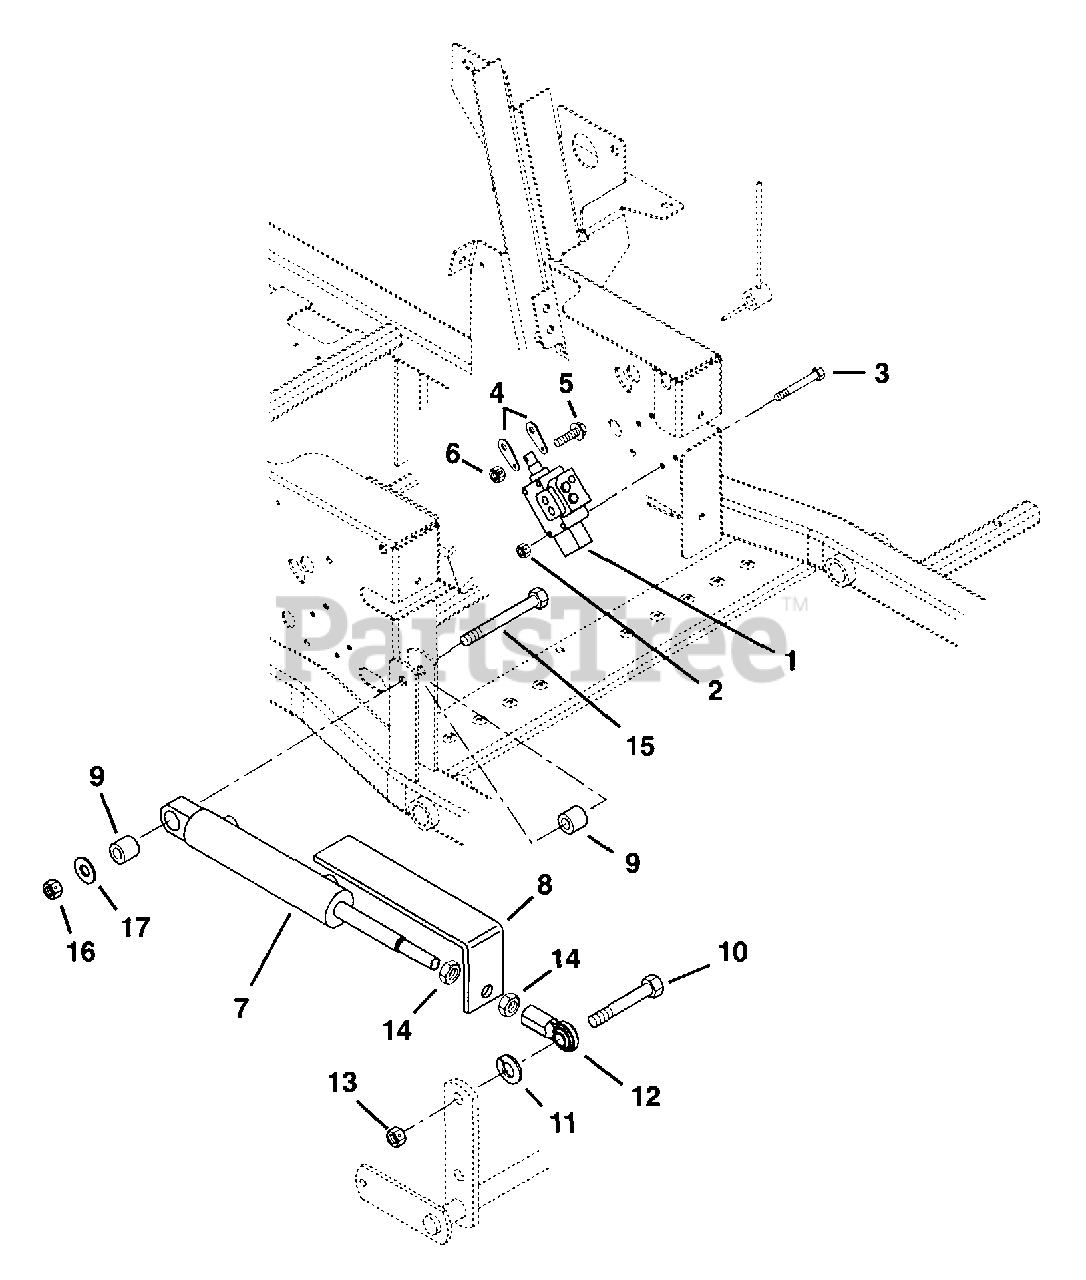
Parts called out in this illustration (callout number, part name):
1	Valve, Hydraulic Lift
2	Nut-Locking-Nylon .25-20
3	Bolt-Hex .25-20 x 2.75 Grade 5
5	Screw-Machine 10-24 x 1.00 Hex Washer Head
6	Nut-Locking-Nylon 10-24 with Insert
7	Cylinder-Hydraulic Lift
8	Strap-Height of Cut Indicator
9	Bushing .516 x 1.000 x 1.050
10	Bolt-Hex .62-11 x 2.25 Grade 8
11	Washer-Lock .62 x .156
12	Rod End-Right Hand-Female 5/8
13	Nut-Locking-Center .62-11
14	Nut-Jam .625-18
15	Bolt-Hex .50-13 x 3.25 Grade 5
16	Nut-Locking-Center .50-13
17	Washer-Flat-Steel .515 x 1.625 x .250
